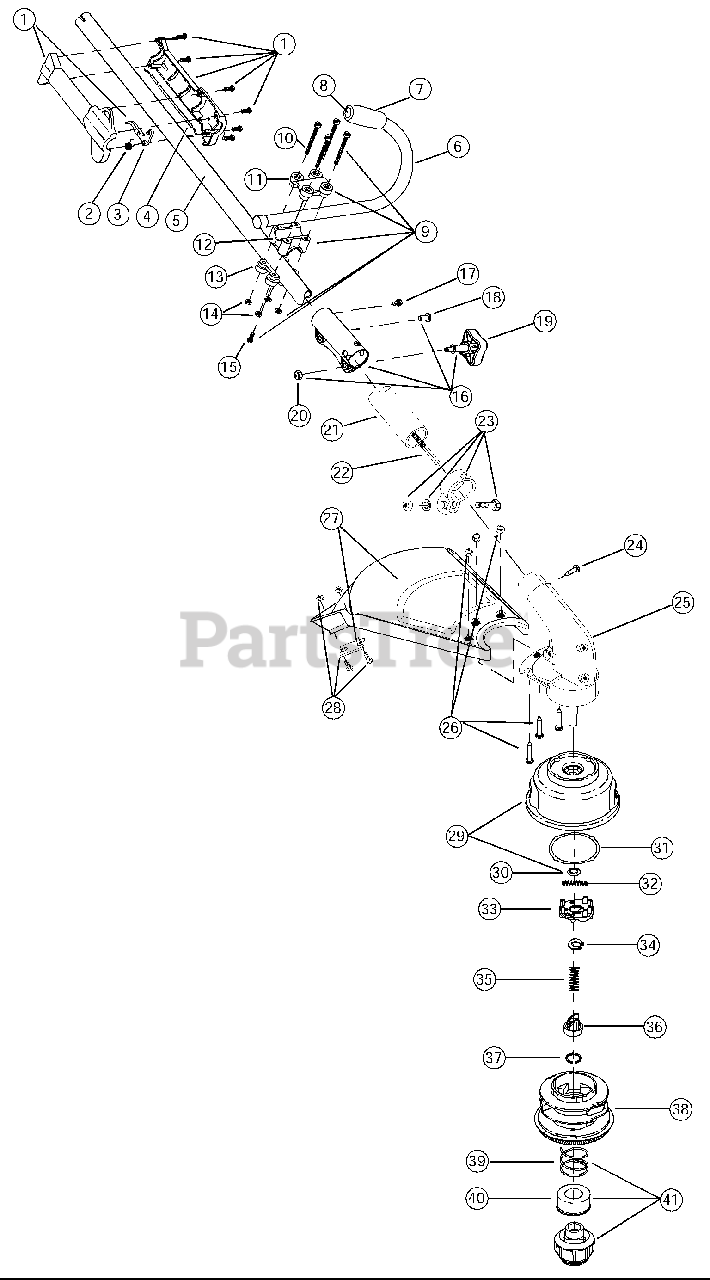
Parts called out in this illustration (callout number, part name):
1	Throttle Housing & Trigger Assembly
2	Throttle Trigger Spring
3	Throttle Trigger
4	Throttle Cable Assembly
5	Upper Drive Shaft Housing Assembly
6	J-Handle Assembly
8	Tube Closure
9	Handle Bracket Assembly
11	Upper Handle Clamp
12	Middle Handle Clamp
13	Lower Handle Clamp
15	Anti-Rotation Screw
16	Click-Link Coupler
19	Adjustment Knob
20	Knob Retaining Nut
21	Lower Drive Shaft Housing Assembly
22	Lower Flexible Drive Shaft
23	Lower Clamp Assembly
24	Anti-Rotation Screw
25	Gearbox Assembly
26	Shield Mounting Hardware
27	Shield and Blade Assembly
28	Blade Assembly
29	Outer Spool Assembly
30	Retainer
31	Thrust Washer
32	Small Spring
33	Slider
36	Plunger
38	Inner Reel
39	Large Spring
40	Foam Seal
41	Bump Knob Assembly
